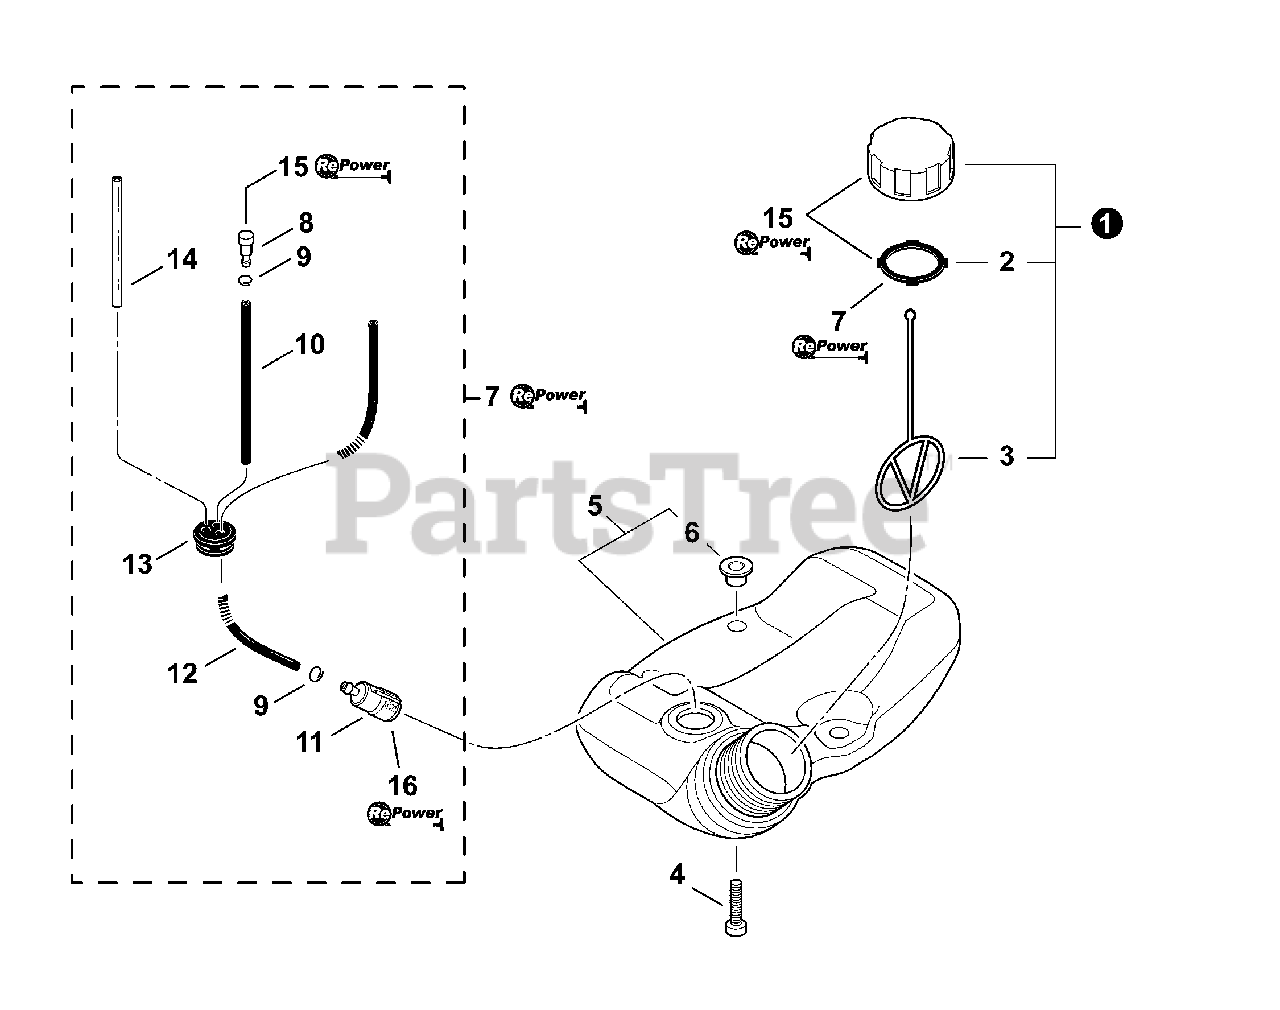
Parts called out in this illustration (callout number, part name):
1	CAP ASSY
2	GASKET, CAP
3	CONNECTOR, CAP
4	SCREW - 5×20
5	FUEL TANK ASSY
7	RePower FUEL SYSTEM KIT
8	VENT, FUEL TANK
9	CLIP - 6
10	PIPE - 3×6×80 -- CLEAR
11	FILTER, FUEL
12	PIPE - 3×5×210 -- BLACK
13	GROMMET
14	PIPE - 3×5×90 -- BLACK
15	Repower CAP AND VENT KIT
16	RePower FILTER KIT
16	RePower TUNE-UP KIT
